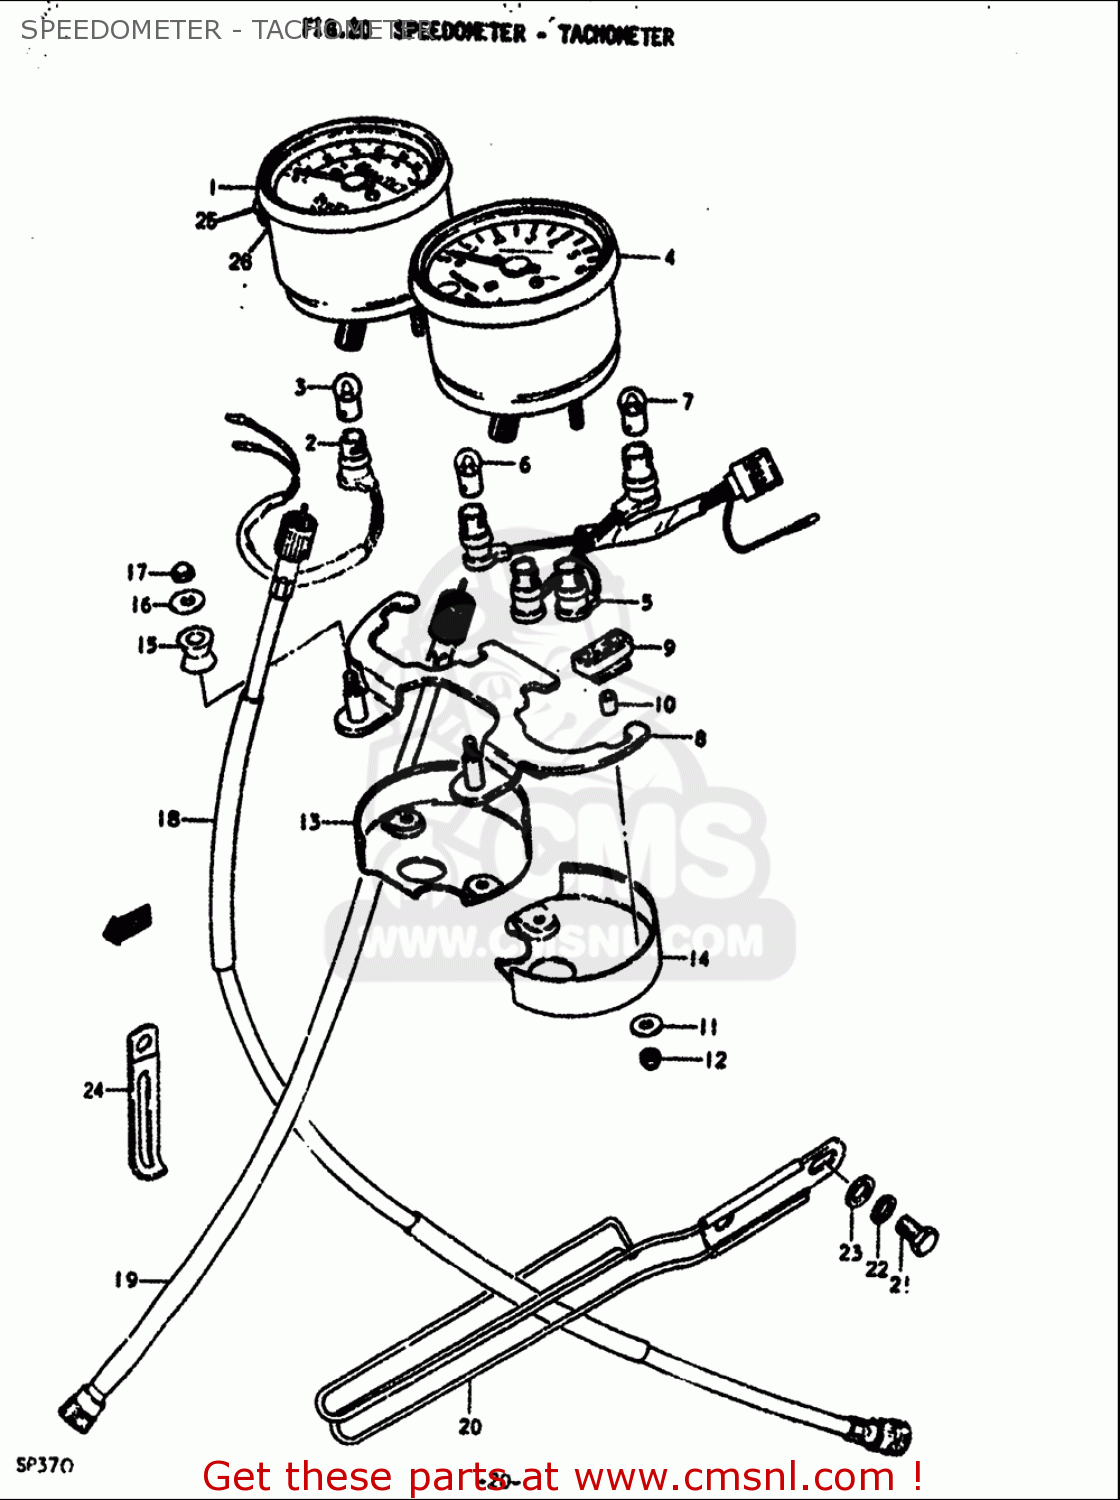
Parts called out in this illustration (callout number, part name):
2	SOCKET,METER
3	BULB(6V/3W)
6	BULB(6V1.7W,STANLEY,A61A)
7	BULB(6V/3W)
10	SPACER
11	WASHER(5.5X16X1.2)
12	NUT
15	CUSHION
16	WASHER(6.5X18X1.6)
17	NUT
18	CABLE ASSY,SPEEDOMETER
19	CABLE ASSY,TACHOMETER
20	GUIDE,CABLE
21	BOLT
22	WASHER,LOCK
23	WASHER
24	CLAMP(L:65)
26	SCREW(2X6)
